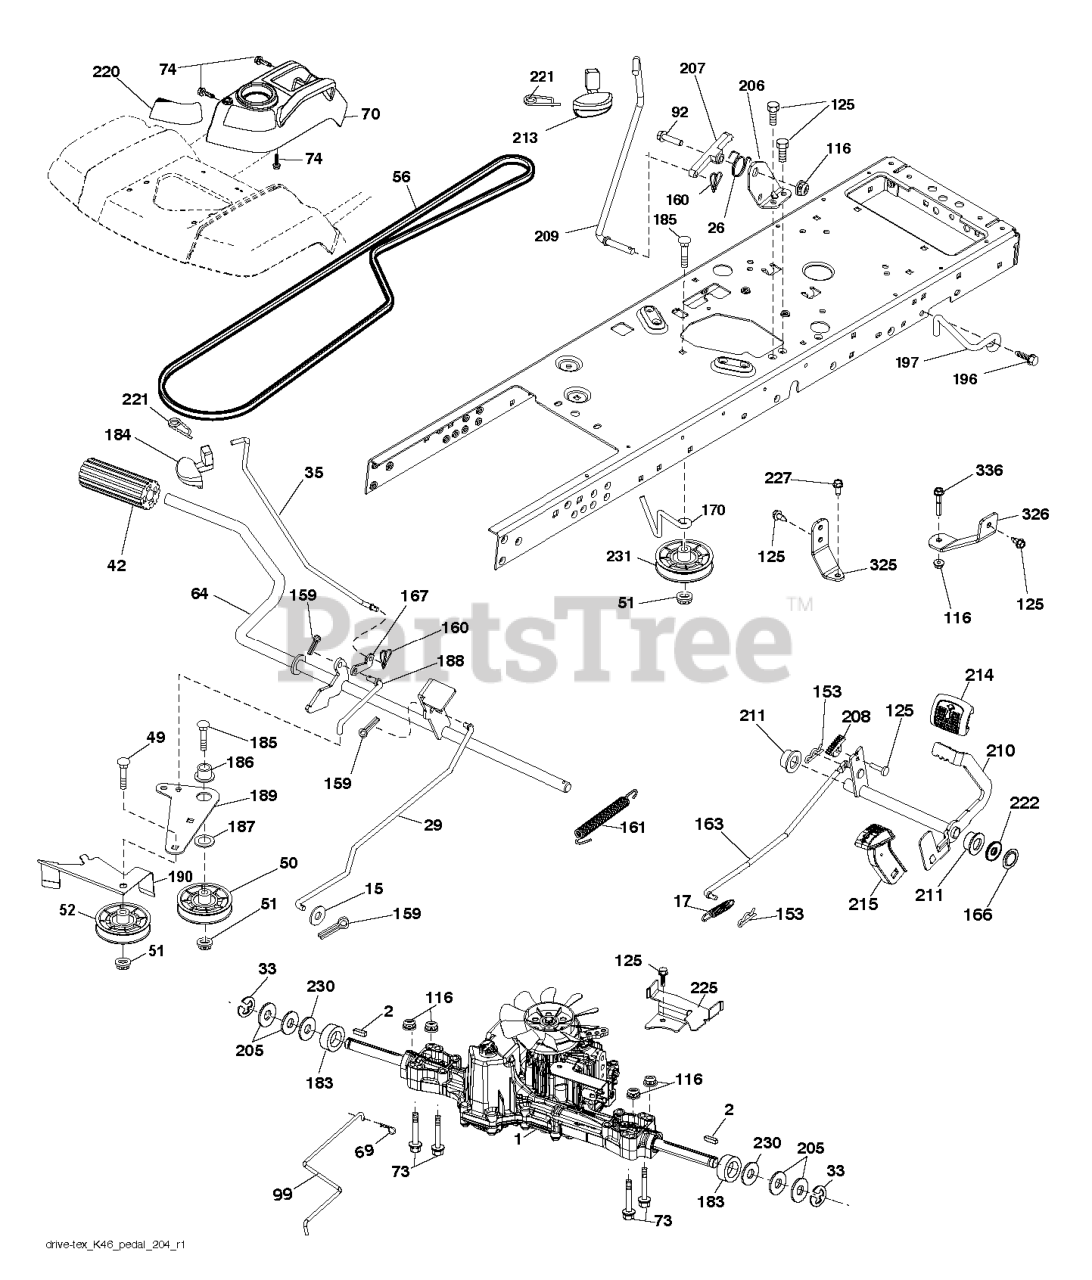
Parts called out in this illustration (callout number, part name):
2	SQUARE KEY
15	WASHER
17	SPRING.BRAKE.K46.GREEN
26	SPRING.RETURN.CRUISE
29	ROD.BRAKE.K46
33	E RING HYT
35	ROD .BRAKE. PARKING. GT. HUSQ.
42	PEDAL COVER T
50	IDLER.FLAT.910.OFFSET
51	NUT LOCK FLG 3/8-16 UNC
52	IDLER.V-GROOVE.910.OFFSET
56	V-BELT.MOWER.92.40.42/K46
64	SHAFT.ASM.PEDAL.BRK.CNTR
69	HAIRPIN.SOFT.ZINC.059X1.125
70	CONSOLE.ASM.RH.GT.FC.HUSQ
73	BOLT
74	SCREW.HI-LO.CONSOLE
92	BOLT
99	ARM.PIVOTING.TCRD.GEN2.5.BAGGE
116	NUT LOCK HEX FLANGE 5/16-18
125	SCREW
153	RETAINER M
159	COTTER PIN
160	RETAINER CLIP
161	SPRING, RETURN LT
163	ROD.CONTROL.K57R.K46
166	NUT.PUSH.625
167	LATCH.BRAKE.SPRING
170	KEEPER.CENTER SPAN.1.688
183	SPACER AXLE
184	HANDLE.PARKING.BRAKE.H (BLK)
186	SPACER.RETAINER
187	WASHER 12/32X2X10GA
188	LINK.CLUTCH.GROUND DRIVE.LONG
189	BELLCRANK.GROUND.DRIVE.TEX.
190	KEEPER.BELLCRANK.DRIVE
196	SCREW 3/8-16X1
197	BRKT.42.FCS.CLUTCH.ANTIROTATIO
206	BRACKET.MOUNT.CRUISE.LATCH
207	LATCH.CONTROL.CRUISE.TEX
208	GEAR.SECTOR.CONTROL.CR
209	ROD.CONTROL.CRUISE.GT.
210	ROCKER.ASM.PEDAL.CONTR
211	BEARING.NYLON
213	KNOB.CONTROL.CRUSIE.HU
214	PEDAL.FORWARD.PAD.TEX
215	PEDAL.COVER.REVERSE.CRD.X428BK
220	REFLECTOR.RH.TEX GT
221	RETAINER.SPRING.CLIP.H
222	WASHER 21/32 X 1-1/4 X 10 GA.
225	KEEPER.BELT.TRANSAXLE.K46
227	SCREW.THDROL.5/16-18X3/4.TTY
230	WASHER.HARDENED
231	IDLER.V-GROOVE.1.688.OFFSET
325	TORQUE.STRAP.K46.LT.LH
326	BRCKT.PNT.TRQ.STP.46.18TIRE.RH
336	BOLT.5/16-18X1-3/4.FLANGED.HEX
